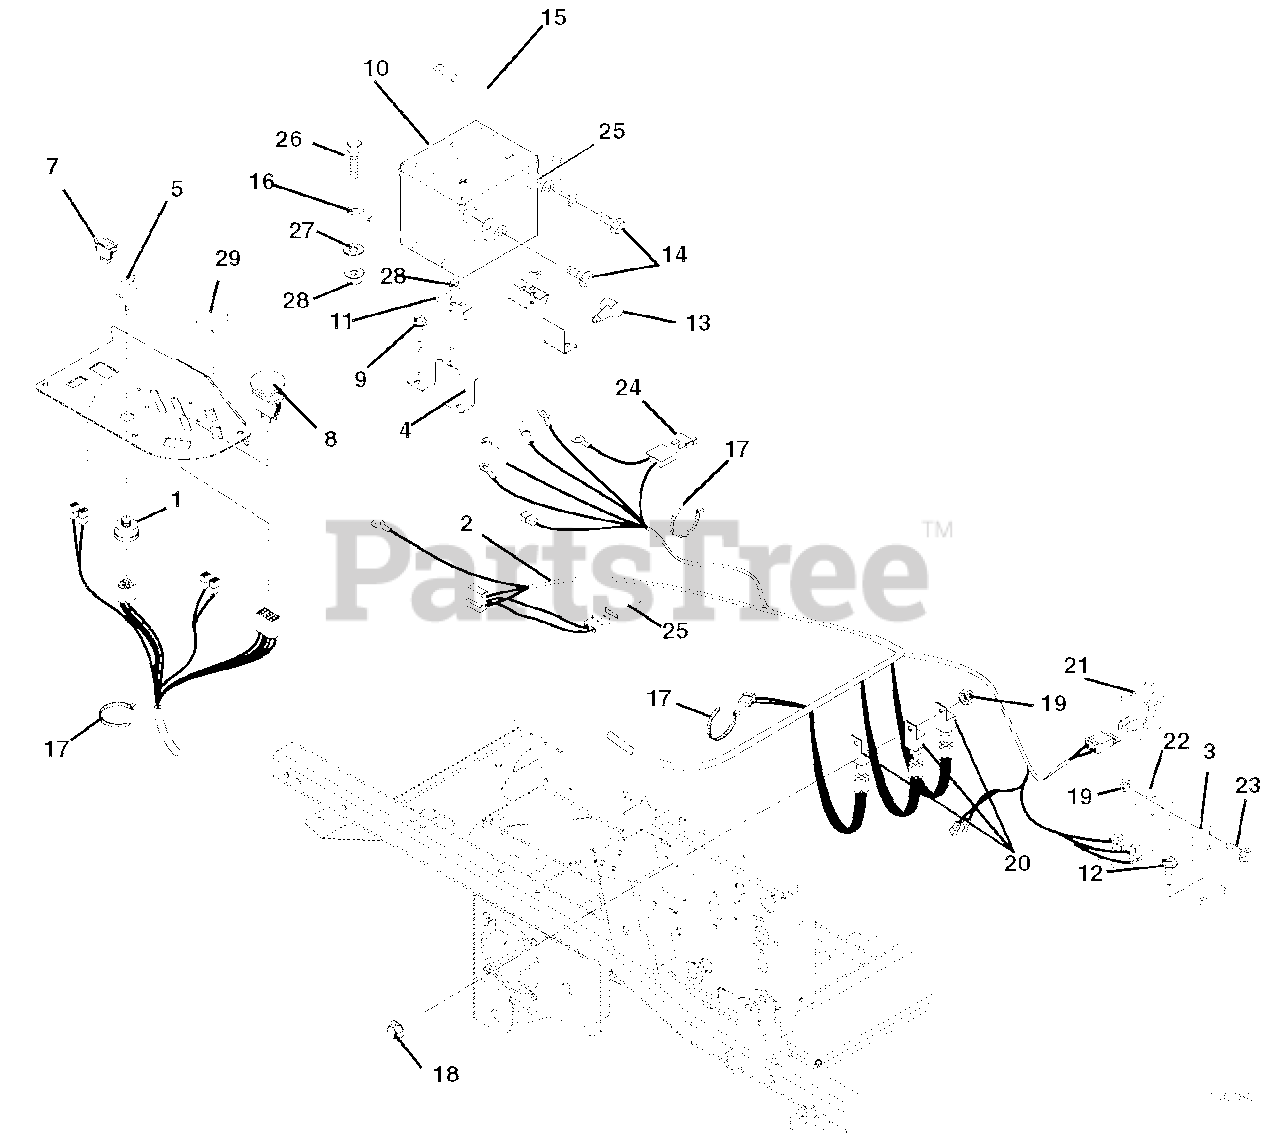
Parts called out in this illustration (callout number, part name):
1	Switch, Ignition
2	Harness, MZ Vertical A/C
3	Mount, Safety Switch
4	Weldment, Battery Support
5	Key, with Shield
6	Ignition Key Set
7	Hour Meter
8	Switch, PTO Clutch
9	Screw-Tapping .38-16 x .75 Hex Washer Head
10	Battery with Tube
11	Bracket, Battery Hold-Down
12	Screw-Tapping .25-20 x .50 Hex Washer Head
13	Battery Terminal Boot, Red
14	Bolt-Hex .25-20 x .75 Grade 5
15	Cable, Positive Battery with Boots
16	Cable, Negative Battery
17	Cable Tie
18	Screw-Machine 10-24 x .50 Hex Washer Head
19	Nut-Locking-Nylon 10-24 With Insert
20	Relay (Included with Harness)
21	Switch, Snap Mounting
22	Switch- Double Pole N.O./N.O.
23	Screw-Machine 10-24 x .75 Hex Washer Head
24	Fuse, 30 Amp (Included with Harness)
25	Diode, Connector Shell
26	Bolt-Hex .31-18 x .75 Grade 5
27	Washer-Flat-Steel .344 x .688 x .065
28	Nut-Locking-Top-Flange .31-18
29	Light, Indicator
